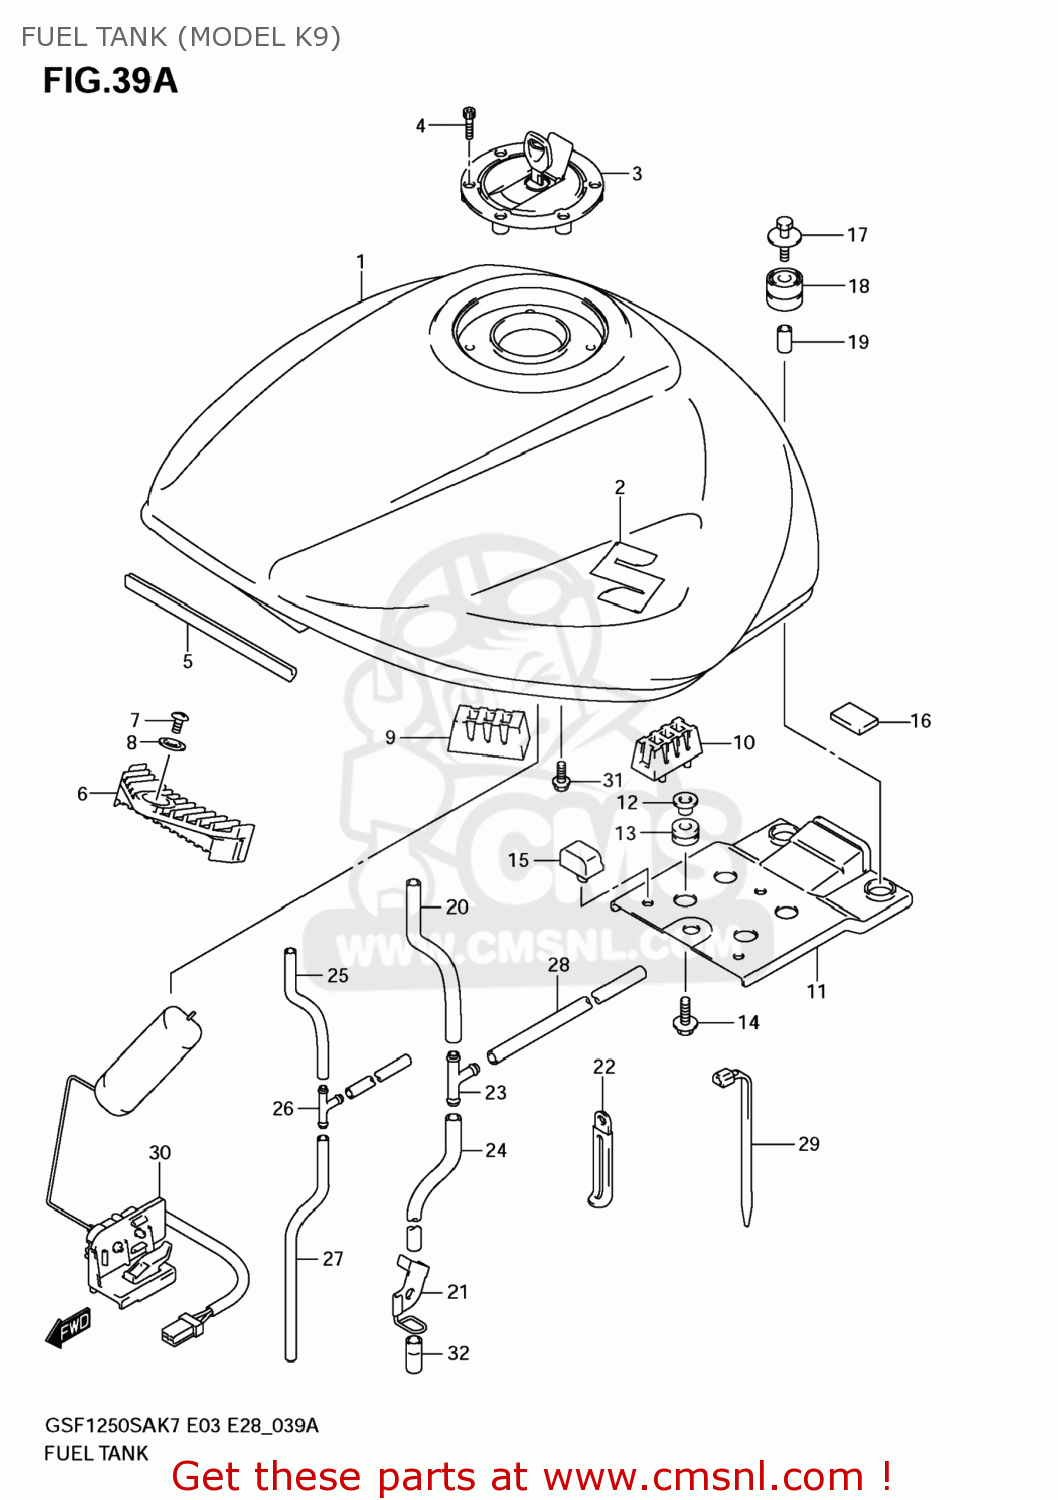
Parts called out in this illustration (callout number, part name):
1	TANK ASSEMBLY,F
2	EMBLEM,S
3	CAP SET,FUEL TANK
4	BOLT(5X20)
5	MOLDING
6	CUSHION,FUEL TANK FR
7	SCREW
8	WASHER
9	CUSHION,SUPPORT(50X25X32)
10	CUSHION,TANK SIDE
11	BRACKET,FUEL TANK RR
12	WASHER
13	CUSHION
14	BOLT(6X20)
15	CUSHION
16	CUSHION,SIDE COVER BRACKET
17	BOLT(6X30)
18	CUSHION,FUEL TANK RR BRKT
19	SPACER(6.5X9X18)
20	HOSE,WATER DRAIN
21	GUIDE,DRAIN HOSE
22	CLAMP(L:97)
23	3-WAY [FILTER TO PUMP)
24	HOSE(7X10.2X600)
25	HOSE,TANK BREA
26	JOINT,3 WAY
27	HOSE(5X8.2X600)
28	HOSE(5X8.2X2000)
29	CLAMP(L:125)
30	GAUGE ASSY,FUEL LEVEL SENDER
31	BOLT
32	HOSE(13.5X16.5X600)
